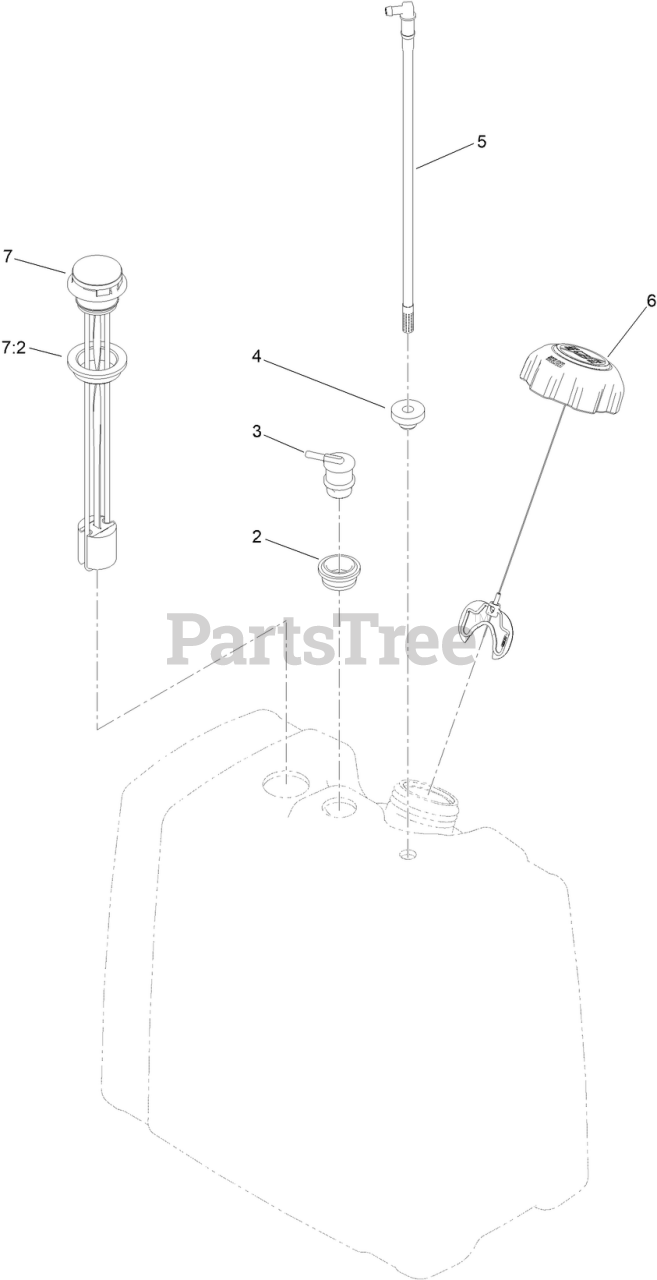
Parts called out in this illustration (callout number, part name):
2	GROMMET
3	VALVE-VENT, FUEL
4	BUSHING
5	PIPE-STAND
6	CAP-FUEL
7	GAUGE ASM
